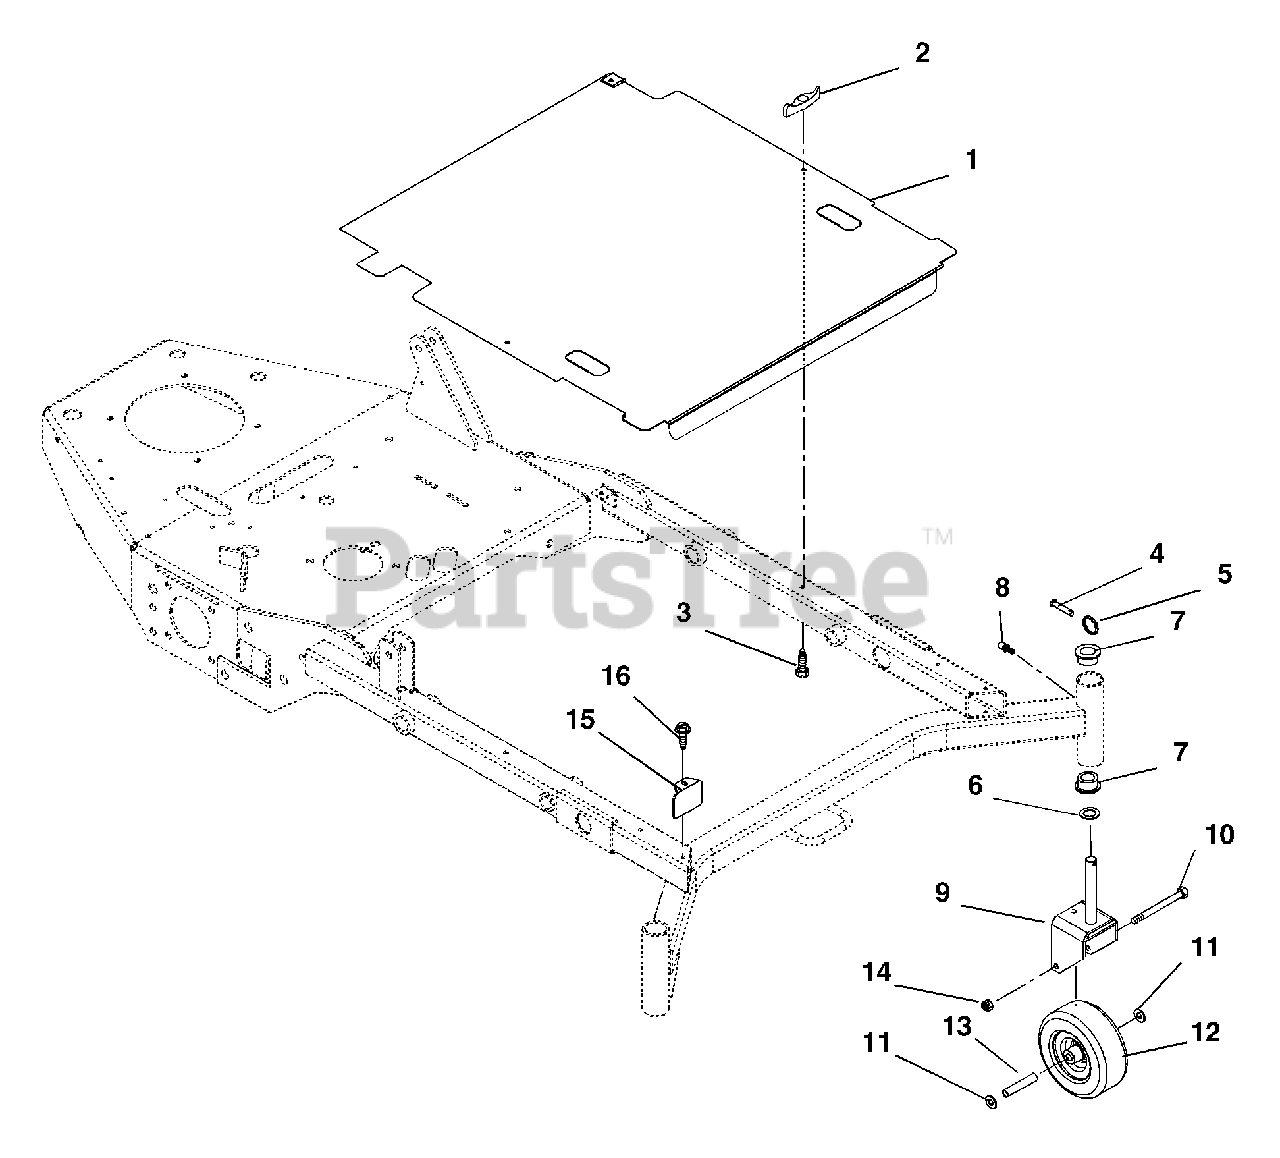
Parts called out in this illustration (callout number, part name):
1	Cover, Mower Deck
2	Knob- Wing .31-18
3	Bolt-Rib Neck .31-18 x 2.50
4	Pin-Clevis .31 x 2.62 Grade 5
5	Ring-Retaining-External 1.062 x 1.25
6	Washer-Hardened-Thrust 1.00 x 1.55 x .03
7	Bushing-Flange 1.020 x 1.385 x .75 x 1.75 Nylon
8	Fitting-Lube .25-28 x .256
9	Weldment, Caster Fork
10	Bolt-Hex .50-13 x 5.50 Grade 5
11	Washer-Hardened Thrust .760 x 1.25 x .094
12	Wheel Assembly 9.00 x 3.50
13	Spacer, .750 x .532 x 4.47
14	Nut-Locking-Center .50-16
15	Cover, Mower Tube
16	Screw-Tapping .25-20 x .50 Hex Washer Head
